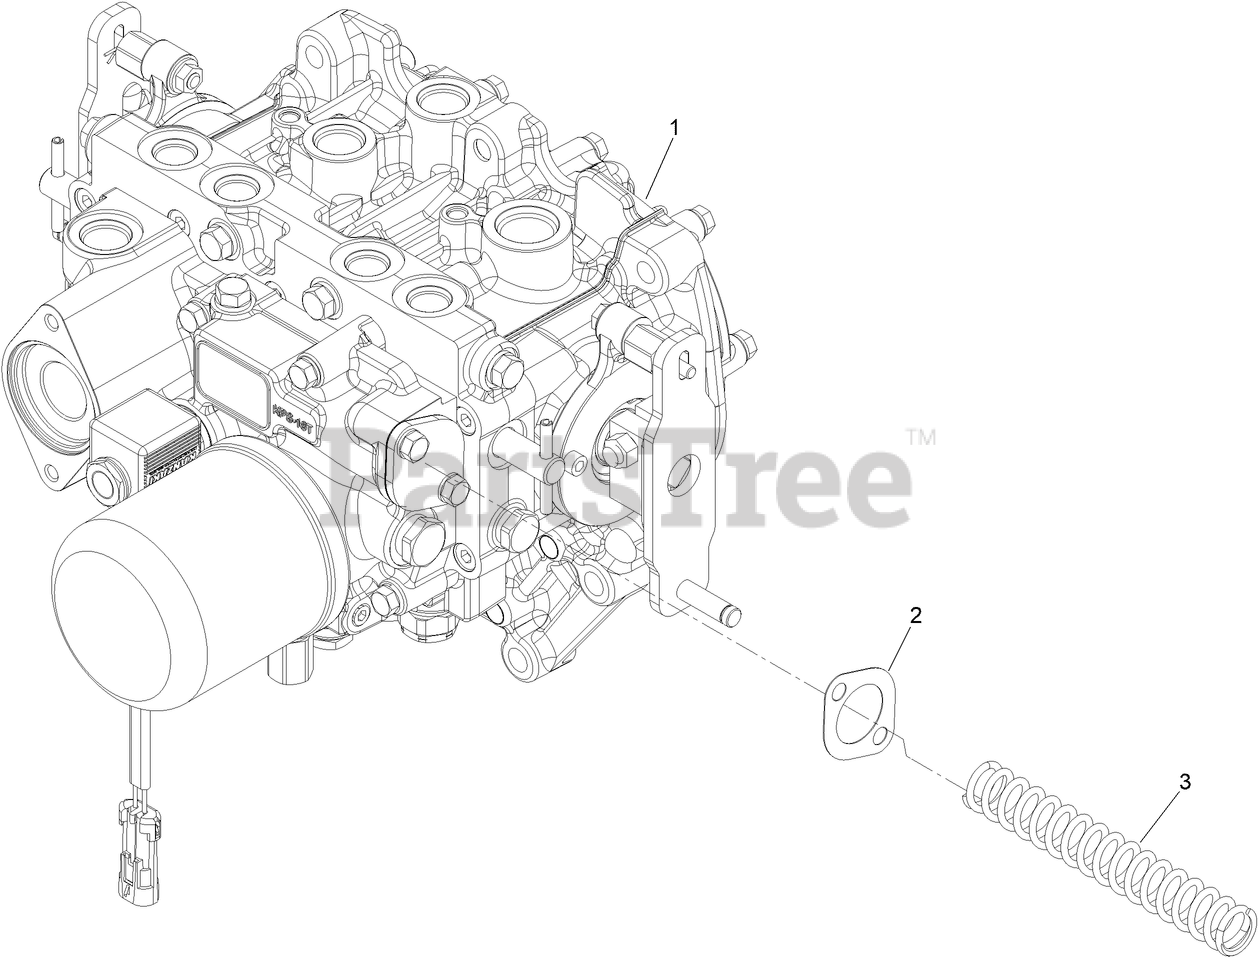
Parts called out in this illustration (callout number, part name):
1	TRANSMISSON ASM
2	GASKET
3	SPRING-COMPRESSION
